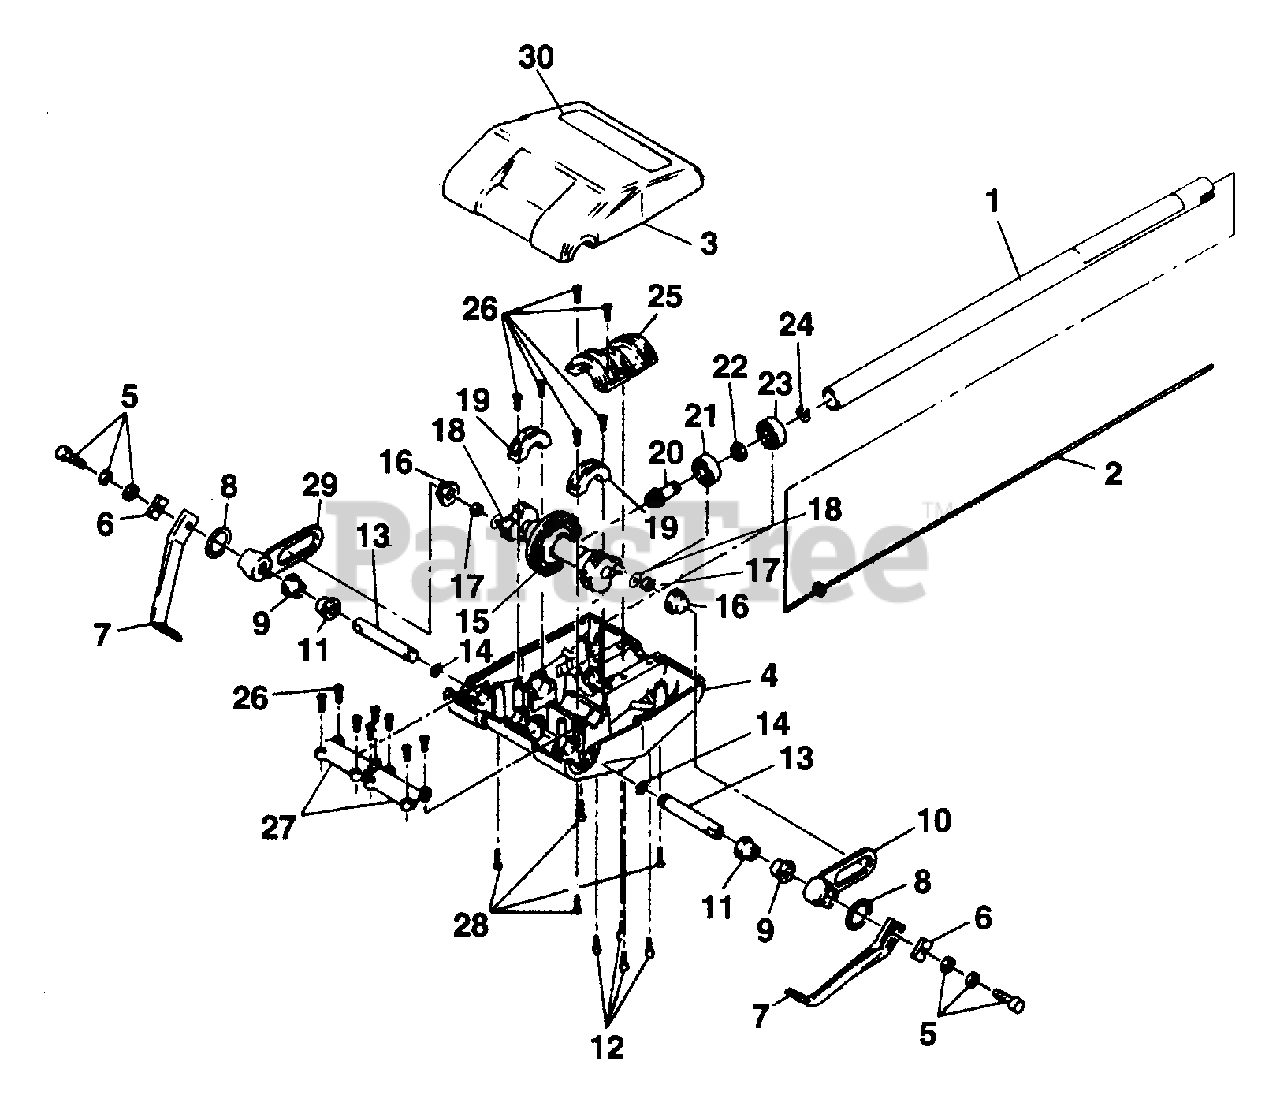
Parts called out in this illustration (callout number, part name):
1	TUBE ASSY
2	FLEX CABLE
3	UPPER COVER
4	LOWER COVER
5	BOLT, SEMS
6	TINE SUPPORT
8	"O" RING
10	ROCKER ARM L.H.
12	SCREW
13	ROCKER SHAFT
14	WIRE RING
15	CRANK ASSY.
16	BEARING CAP
17	NEEDLE BEARING
18	WASHER
19	CRANKSHAFT CLAMP
20	PINION GEAR
21	BEARING
24	SNAP RING
25	SHAFT CLAMP
26	SCREW
27	SHAFT CLAMP
28	SCREW
29	ROCKER ARM R.H
30	LABEL, MODEL
